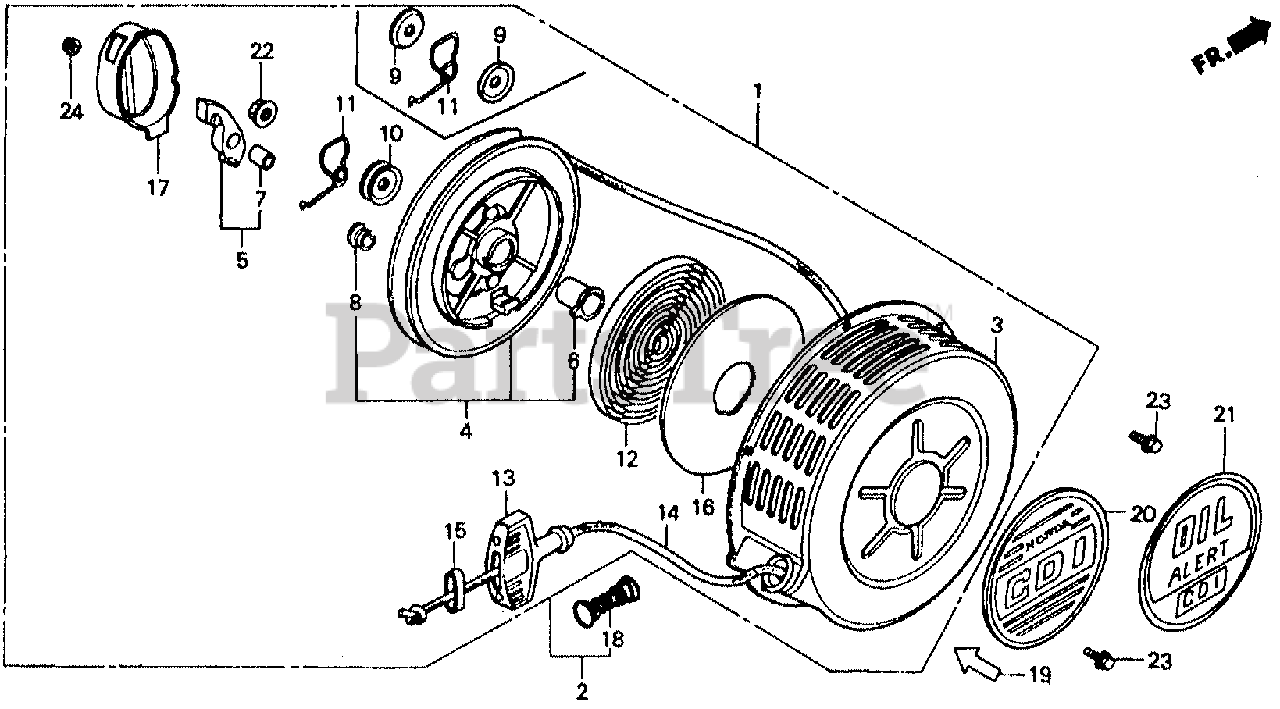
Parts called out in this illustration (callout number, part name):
1	STARTER ASSY., RECOIL *R8* (BRIGHT RED)
2	STARTER ASSY., RECOIL
3	CASE, STARTER *R8* (BRIGHT RED)
3	CASE, STARTER
4	REEL, STARTER
5	RATCHET
6	BOSS, REEL
7	BUSH, RATCHET
8	BUSH, REEL STARTER
9	PLATE, FRICTION
10	PLATE, FRICTION
11	SPRING, FRICTION
12	SPRING, RETURN
13	GRIP, STARTER
14	ROPE, STARTER (#5X55")
15	SUPPORT, GRIP
16	PLATE, SIDE
17	COVER, REEL STARTER
18	SPRING, ROPE GUIDE
19	MARK, STARTING
20	MARK, C.D.I.
22	NUT, SELF-LOCK (8MM)
23	BOLT, FLANGE (6X8)
24	NUT, FLANGE (5MM)
